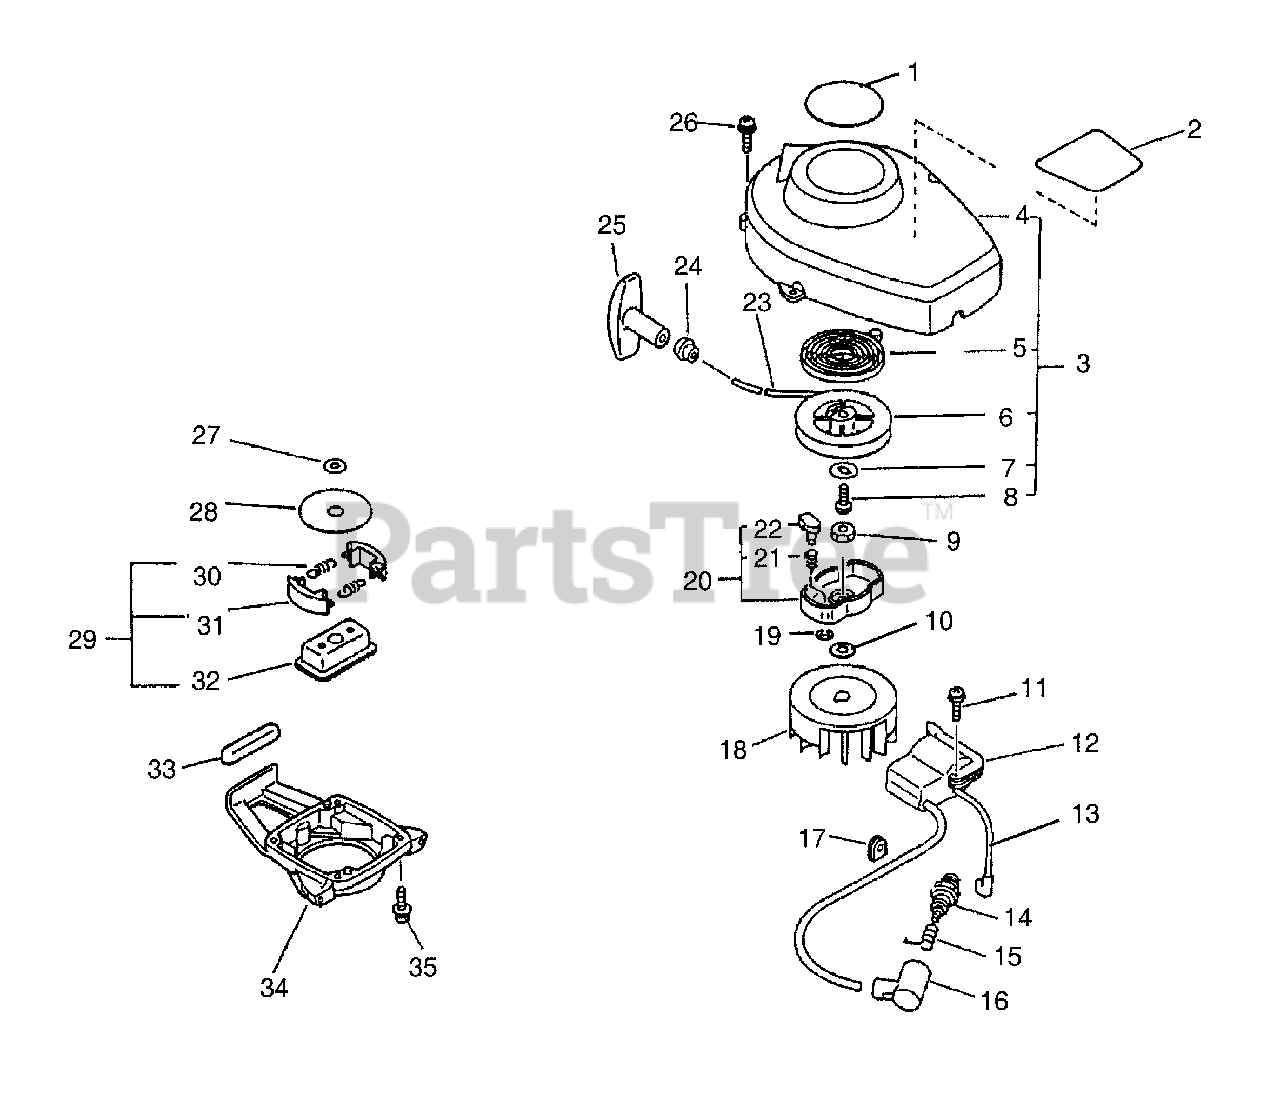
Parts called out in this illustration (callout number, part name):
1	LABEL, MODEL
2	LABEL, CAUTION
3	STARTER ASSY
4	CASE, STARTER
5	SPRING, RECOIL
6	REEL, ROPE
7	WASHER
8	SCREW
10	WASHER, SPRING 8
11	SCREW 4×22
12	COIL, IGNITION
13	LEAD
14	SPARK PLUG - BPM-7Y
14	SPARK PLUG - BPMR7A
15	TERMINAL, SPARK PLUG
16	CAP, SPARK PLUG
18	FLYWHEEL
19	E-RING 4
20	STARTER PAWL ASSY
21	SPRING, RETURN
22	PAWL, STARTER
23	ROPE, STARTER
24	GUIDE, ROPE
25	GRIP, STARTER
26	BOLT 4×16
27	WASHER, CLUTCH
28	PLATE, CLUTCH
29	CLUTCH ASSY
30	SPRING, CLUTCH
31	SHOE, CLUTCH
32	HUB, CLUTCH
33	CUSHION, FUEL TANK
34	HOUSING, CLUTCH
35	BOLT 4×16
